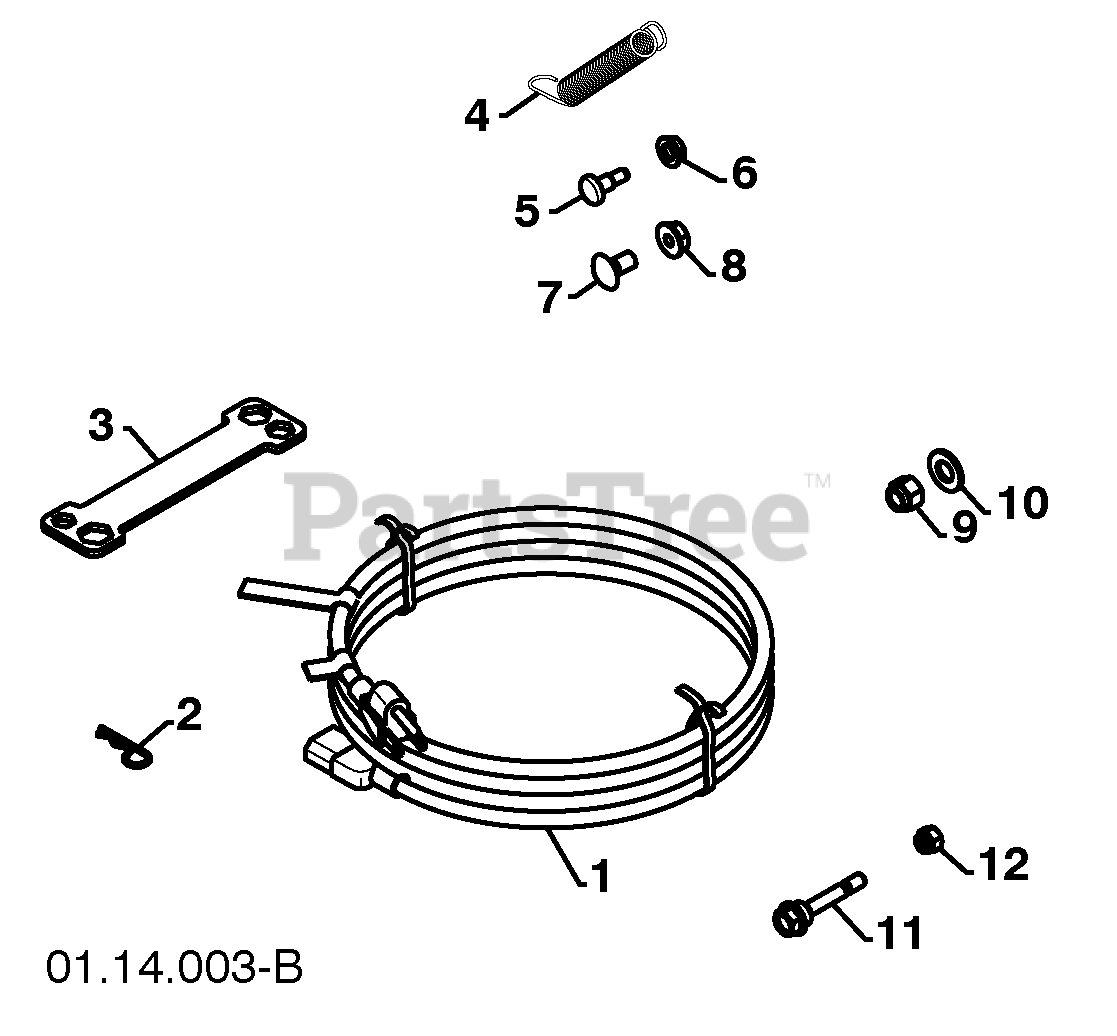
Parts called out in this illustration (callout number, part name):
1	POWER CORD
2	RETAINER PIN
3	WRENCH
4	REMOTE SPRING
5	SHOULDER BOLT 1/4-20
6	LOCKNUT 1/4-20
7	CARRIAGE BOLT 5/16-18 X 5/8
8	LOCKNUT 5/16-18
9	LOCKNUT 3/8-16
10	WASHER 3/8
11	SHEAR BOLT 1/4-20 X 1-13/16
12	LOCKNUT 1/4-20
